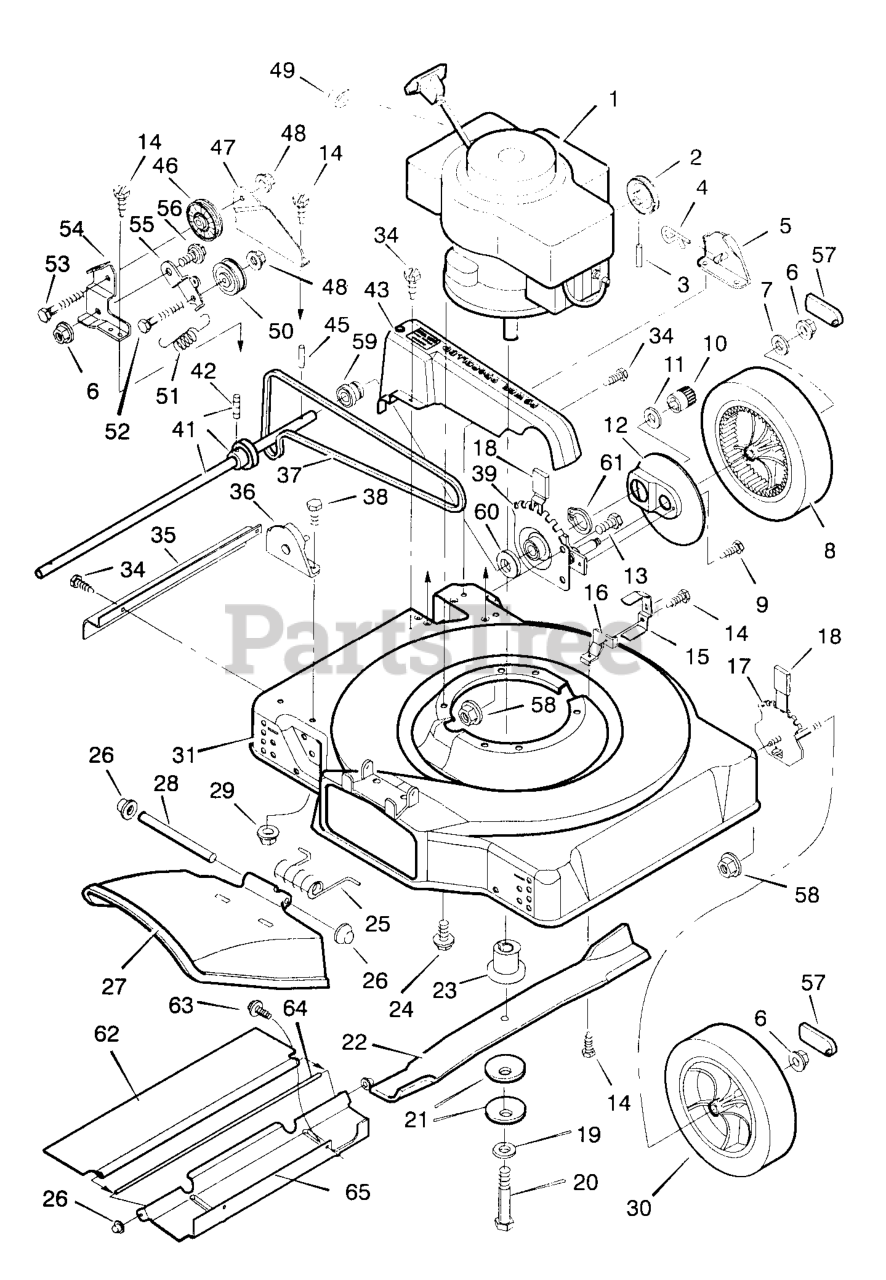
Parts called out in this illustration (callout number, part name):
1	Engine
3	Pin, Spring
4	Pin, Hair
5	Bracket, Left Handle
6	Nut
7	Washer
8	Wheel, Drive
10	Gear, Right Pinion
12	Cover, Dust
13	Bolt, Hex
15	Guide, Belt
16	Belt Guide, Briggs
17	Height Adjuster, Front
21	Washer, Belleville
23	Adapter, Blade
24	Bolt, Engine
25	Spring, Torsion
26	Push On Cap
27	Deflector, Chute
29	Nut
30	Wheel and Tire, Front
31	Housing
35	Guard, Axle
36	Bracket, Right Handle
37	Belt, Briggs & Stratton
39	Height Adjuster, Left
41	Axle, Pulley & Setscrew
42	Setscrew
43	Belt Guard, Briggs
45	Pin, Drive
46	Pulley, Idler
47	Support, Idler
48	Nut
49	Stop, Rope
50	Pulley, Idler
51	Spring, Extension
52	Bolt, Hex
53	Bolt, Hex
54	Bracket, Idler
55	Arm, Idler
56	Bolt, Shoulder
57	Cap, Hub
58	Nut, Flange
59	Bearing and Retainer
60	Washer, Belleville
61	Retainer Ring
62	Guard, Rear
64	Rod, Guard
65	Extension, Rear
